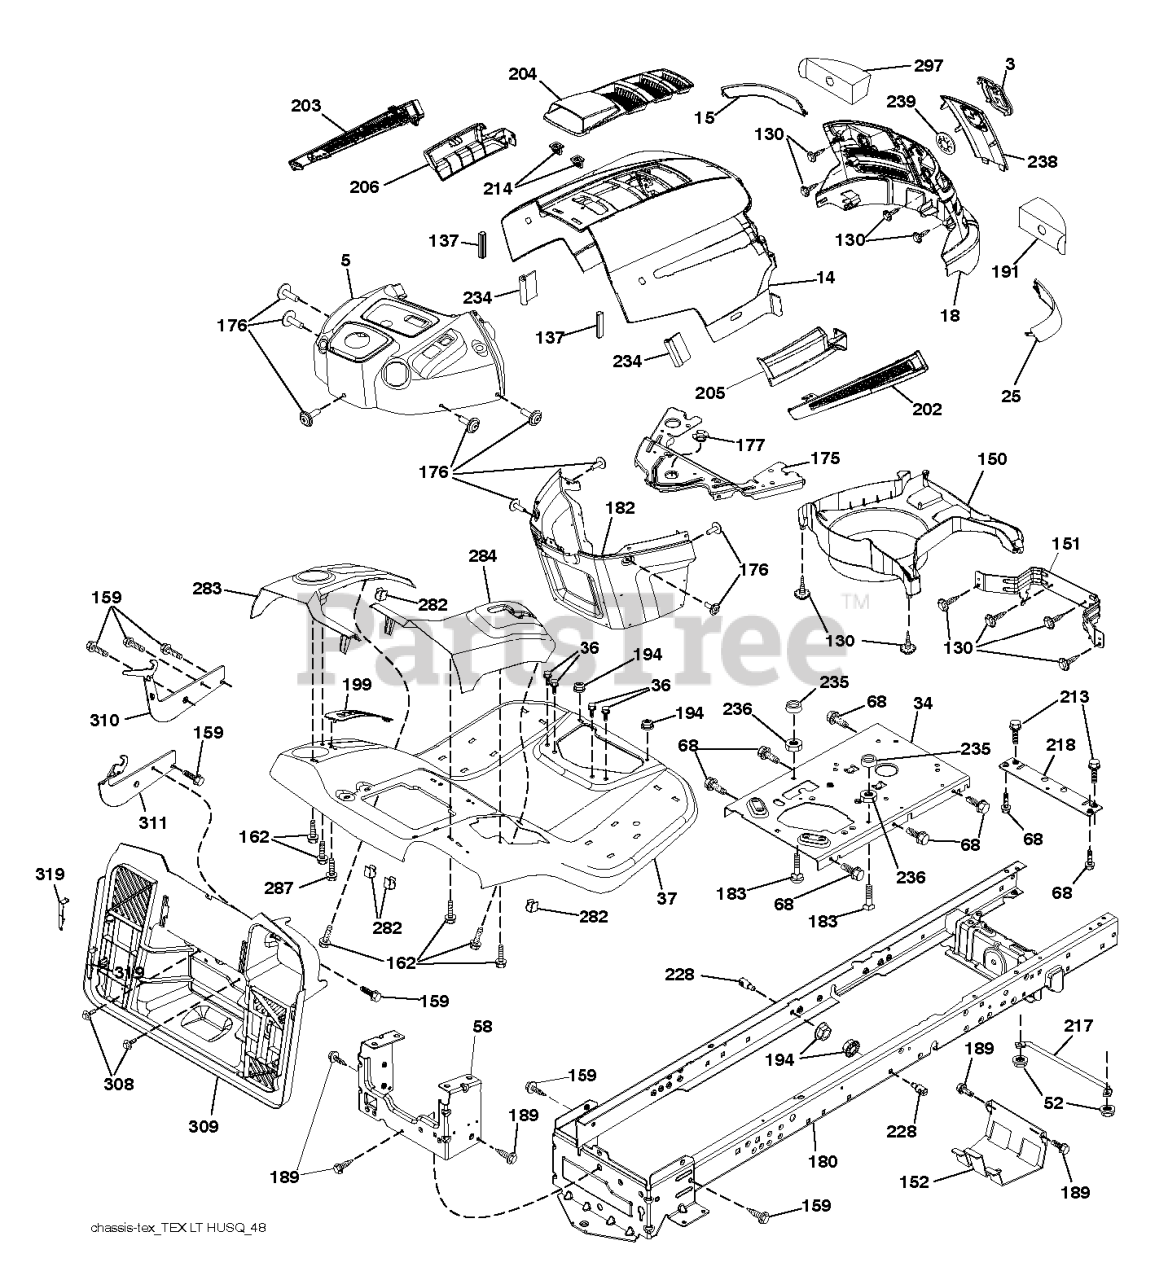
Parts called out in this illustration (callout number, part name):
3	RP LOGO
5	DASH
14	HOOD
15	LENS.HUSQVARNA LT.LH
18	RP GRILLE/LENS ASM.
25	LENS.HUSQVARNA LT.RH
34	PLATE.ENGINE.WELDED.CHASSIS
36	SCREW 5/16"
37	FENDER.PNT.SRD.30R
52	LOCKNUT
58	DRAWBAR UPPER 2PC SMALL FENDER
68	Screw 5/16-18 x 1/2 Hex, Self Tapping 5/16-18 x 1/2
130	SCREW.#10 X 0.750.BOS
137	BUMPER DASH
151	BRACKET PIVOT
152	SHIELD.BROWNING.W/TEX
159	SCREW, 3/8-16X3/4
162	SCREW.HI-LO.CONSOLE
175	CROSSMEMBER
176	SCREW.#10-24X5/8.RN.QU
177	BUSHING STEERING
180	CHASSIS.WLDMNT.14GA.2PC.18".TI
182	DASH.LOWER.PREDATOR LT
183	BOLT.5/16-18X1-1/4 FULL.THREAD
189	SCREW
191	INSERT REFLECTIVE
194	NUT LOCK HEX FLANGE 5/16-18
199	PLATE DECK LIFT
202	VENT SIDE HOOD RH
203	VENT SIDE HOOD LH
204	VENT TOP HOOD
205	SKIRT SIDE RH
206	SKIRT SIDE LH
213	BOLT
214	CLIP.RETAINER.TINNER.
217	ROD.PIVOT.HOOD
218	X-PIECE.HOOD.STOP.NON/
228	STUD.FASTNER.W/ANTI-ROTATE
234	BUMPER.HOOD.TEX.HUSQVARNA
235	SPACER FENDER
236	NUT.CENTERLOCK.5/16-
238	TRIM
282	CLIP.RETAINER.CONSOLE.LT.HUSQ
283	CONSOLE.DCKLFT.SRD.BGR
284	CONSOLE.SHFT.SRD.RH.PE
287	SCREW 1/4X20
297	INSERT.REFLECTIVE.RH.
308	BOLT.5/16-18UNCX3/4 W/SEMS.BLK
309	BACKPLATE.BAGGER.V2.SRD
310	Bracket Hangar Bag LH
311	Bracket Hangar Bag RH
319	BRACKET.ACTUATOR.BAGGER.SRD
